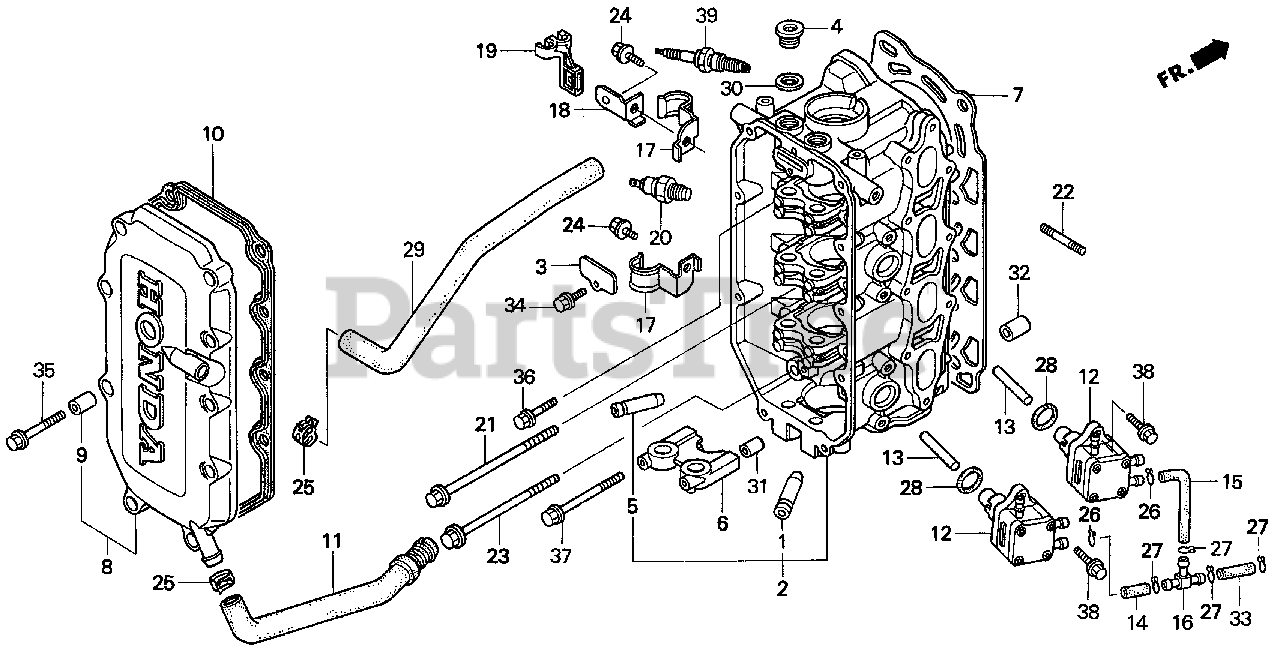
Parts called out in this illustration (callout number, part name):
1	GUIDE, VALVE (OS)
2	CYLINDER HEAD *NH8* (DARK GRAY)
3	PLATE, OIL CHAMBER
4	BOLT, SEALING (20MM)
5	GUIDE, IN VALVE
6	HOLDER, CAM THRUST
7	GASKET, CYLINDER HEAD
8	COVER, CYLINDER HEAD
9	COLLAR, HEAD COVER
10	GASKET, HEAD COVER
12	PUMP ASSY., FUEL
13	LIFTER, FUEL PUMP
14	TUBE B, FUEL
15	TUBE C, FUEL
17	CLAMP, HOSE
18	STAY A, IGNITION WIRE CLAMP
19	CLAMP A, IGNITION WIRE
20	SWITCH ASSY., THERMOSTAT
21	BOLT-WASHER (10X140) (SAGA)
22	BOLT, STUD (8X22)
23	BOLT-WASHER (10X120.5)
24	BOLT, FLANGE (6X12)
25	CLAMP, TUBE (D22)
26	CLIP, TUBE (B10)
27	CLIP, TUBE (B12)
28	O-RING (20.8X2.4)
29	TUBE, BREATHER
30	WASHER, DRAIN PLUG (20MM)
31	PIN A, DOWEL (8X14)
32	PIN, KNOCK (12X16)
33	BULK HOSE, FUEL (7.5X8000) (7.3X55)
34	BOLT, FLANGE (6X12)
35	BOLT, FLANGE (6X35)
36	BOLT, FLANGE (8X40)
37	BOLT, FLANGE (6X80)
38	BOLT, FLANGE (6X20)
39	SPARK PLUG (DR7EA) (NGK)
39	SPARK PLUG (X22ESR-U) (DENSO)
